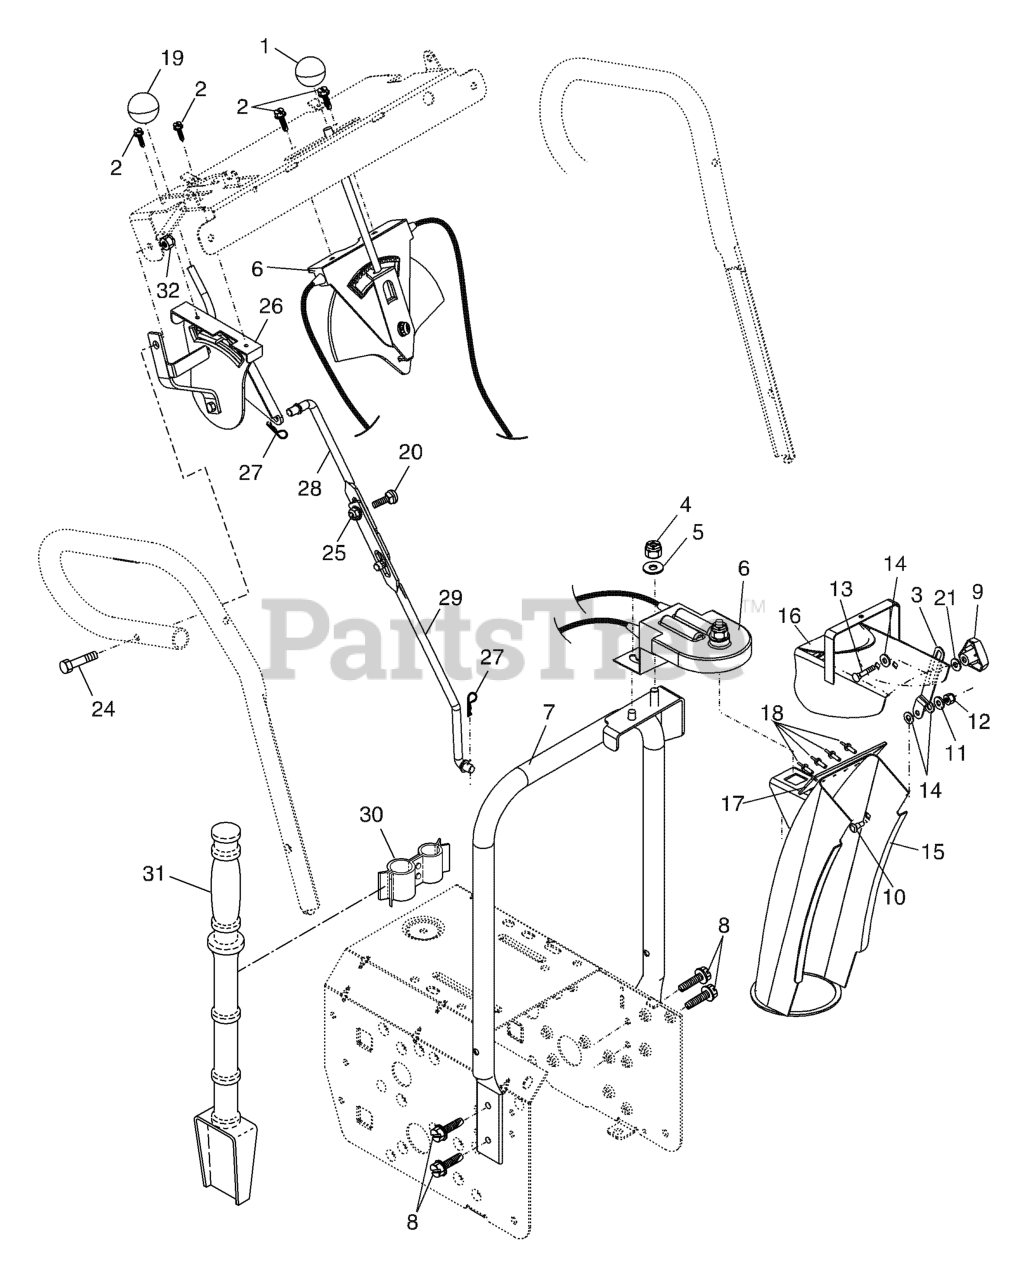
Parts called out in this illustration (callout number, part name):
1	KNOB, LEVER
2	SCREW #10-24 X 5/8
3	STRAP, CHUTE
4	NUT
5	WASHER
6	CONTROL ASSY, CHUTE ROTATER
7	SUPPORT CHUTE ROTATER
8	SELF-TAPPING SCREW 5/16-18X3/4
9	KNOB.SKID.PLATE
10	SHOULDER BOLT
11	WASHER
12	LOCKNUT.NYLOC.1/4-20
13	BOLT
14	WASHER, NYLON FRICTION
15	CHUTE ASSY
16	DEFLECTOR.WELDMENT.PNT.ORANGE
17	SEAL, DEFLECTOR
18	RIVET BLIND
19	RP KNOB, SPEED CONTROL LEVER
20	BOLT
21	WASHER.20X8.5
25	NUT.FLANGE.5/16
26	LEVER ASSEMBLY, SPEED CONTROL
27	SPRING RETAINER
28	ROD, UPPER SPEED CONTROL
29	ROD, LOWER SPEED CONTROL.SNOW
30	CLAMP.ASM.CLEANOUT.TOOL.SNOW
31	CLEAN OUT TOOL
32	NUT.71038.31-18.HEX.NYLOCK
